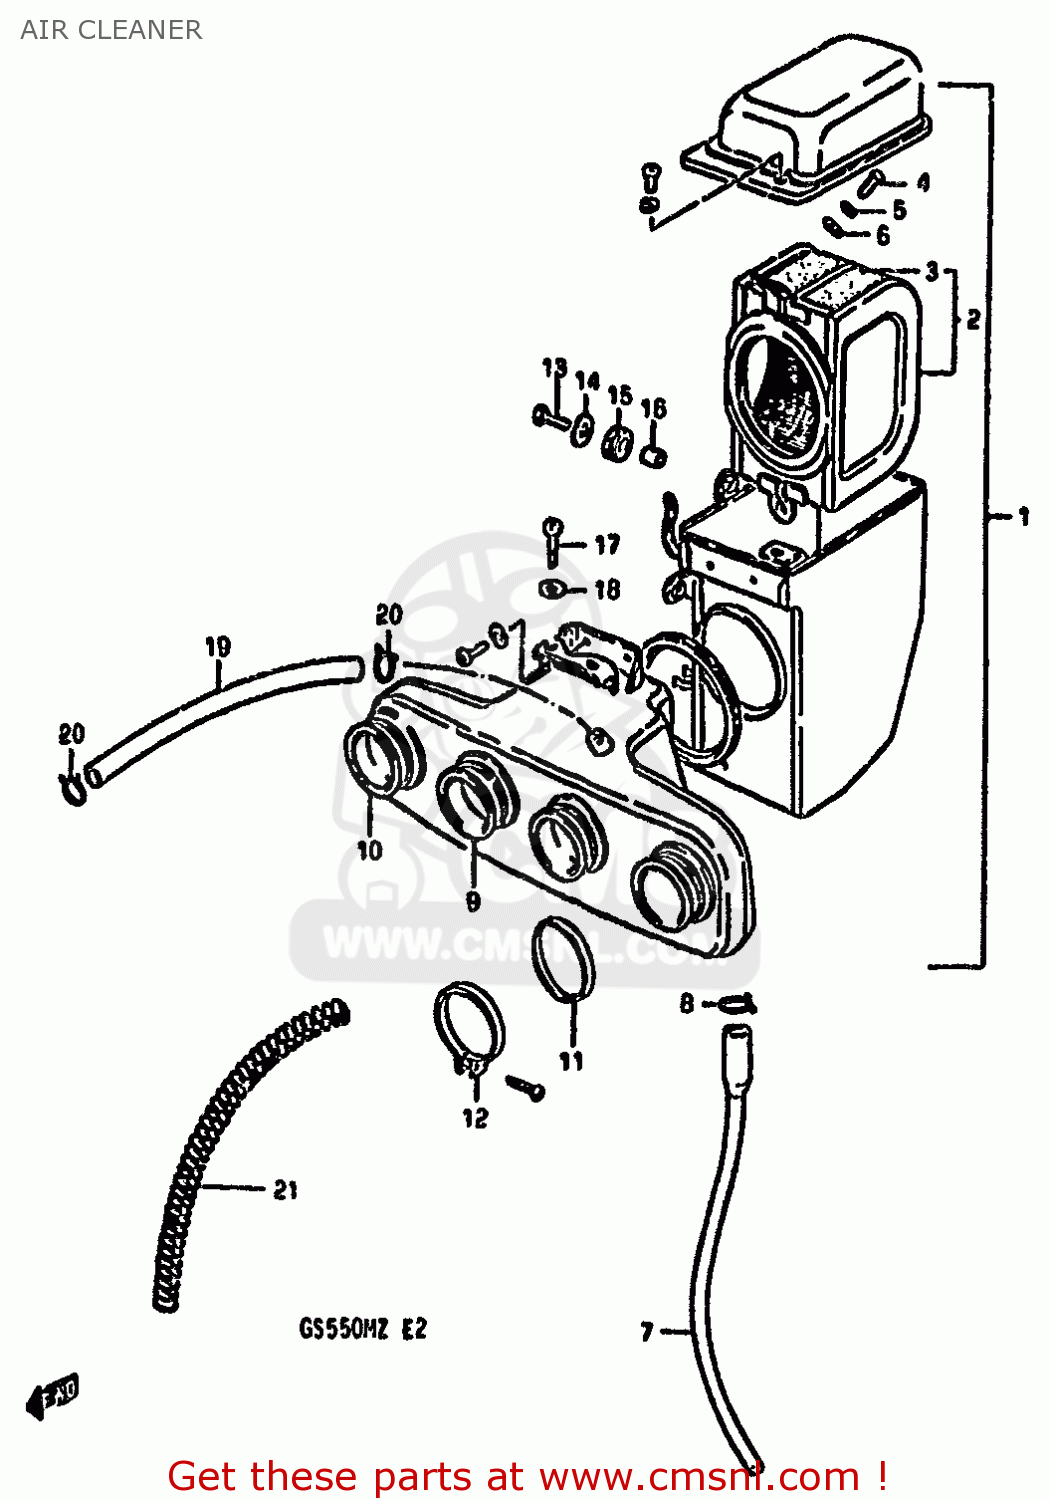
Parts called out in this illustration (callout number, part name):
1	CLEANER ASSEMBLY,AIR
2	FILTER ASSY
3	FILTER
4	SCREW
5	LOCK WASHER
6	WASHER
7	DRAIN TUBE
8	CLIP
9	TUBE,AIR CLEANER OUTLET A
10	TUBE,AIR CLEANER OUTLET B
11	RING,CARBURETOR AIR INLET HOSE
12	CLAMP
13	BOLT
14	WASHER
15	CUSHION
16	SPACER (6.1X9X9)
17	SCREW 6X12
18	WASHER
19	HOSE
20	CLIP
21	SPRING
